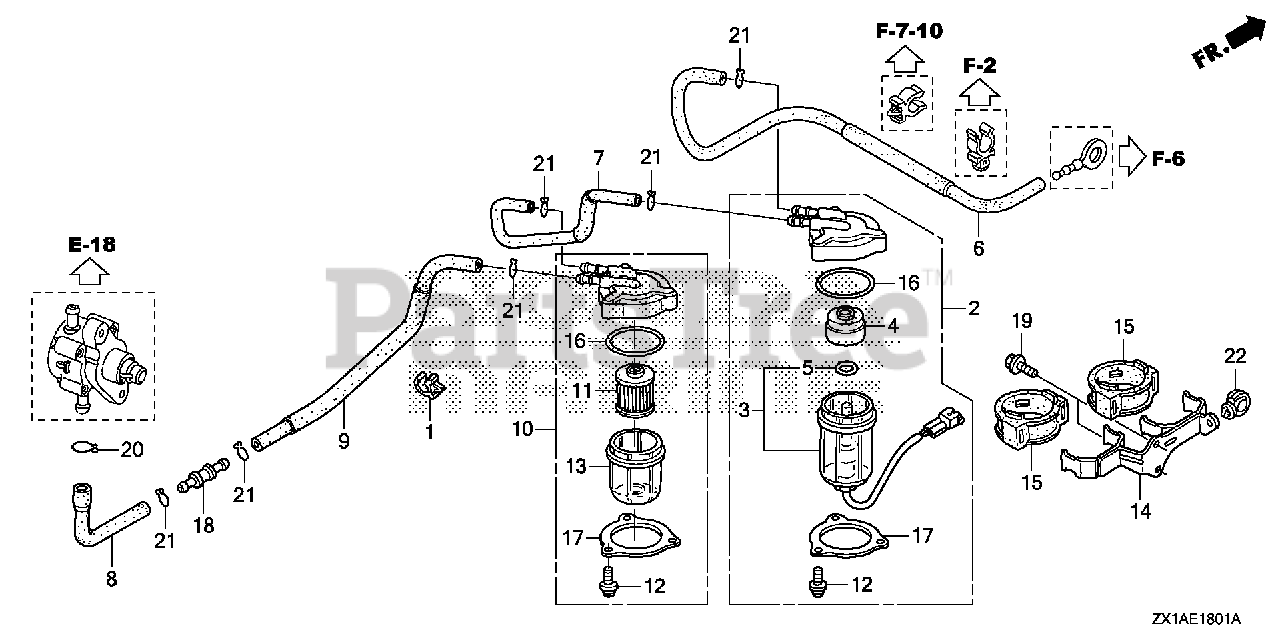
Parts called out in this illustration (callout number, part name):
1	CLIP, TUBE
2	SEPARATOR ASSY., WATER
3	CUP SET, WATER SEPARATOR
4	BUFFER, PLATE
6	TUBE A, FUEL (FKM)
7	TUBE C, FUEL
8	TUBE D, FUEL
9	TUBE E, FUEL
10	FILTER, FUEL
11	FILTER, FUEL
12	SCREW, PAN (5X12)
13	CUP, FUEL STRAINER
14	STAY, FUEL STRAINER
15	SUSPENSION, STRAINER
18	JOINT, FUEL TUBE
19	BOLT, FLANGE (6X14)
20	CLIP, TUBE (B1 14.5)
21	CLIP, TUBE (B12)
22	CLIP, WIRE HARNESS (25MM)
